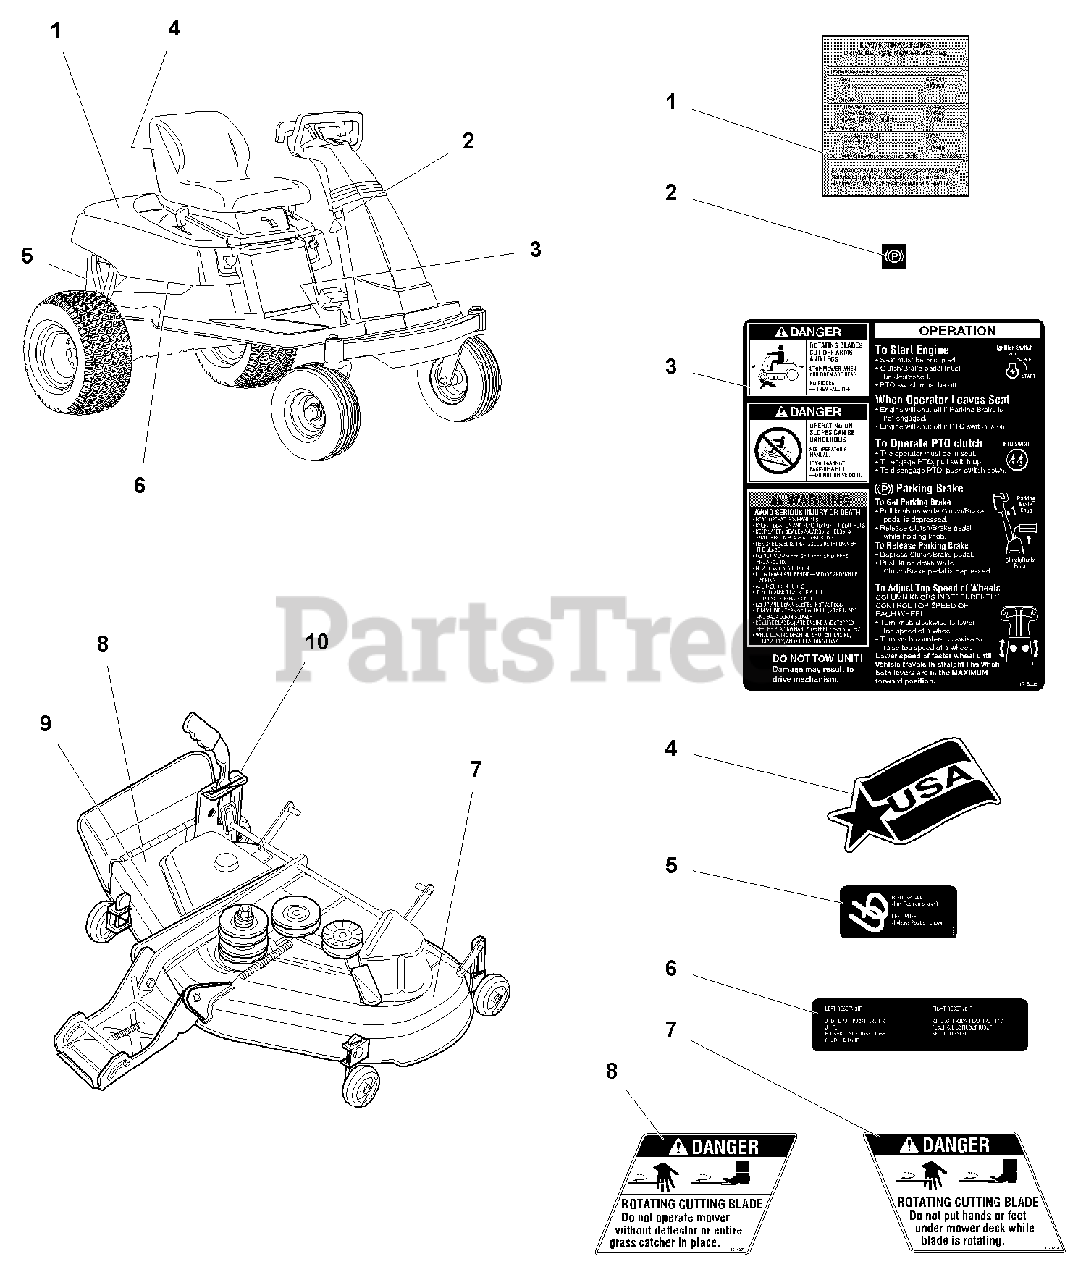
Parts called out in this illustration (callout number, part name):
1	DECAL, Belt/Blade (under Seat Deck)
2	DECAL, Parking Brake
3	DECAL, Operating Instructions
4	DECAL, Logo, USA
5	DECAL, Transmission Release
6	DECAL, Oil Reservoir
7	DECAL, Danger, Rotating Cutting Blade
8	DECAL, Danger, Chute in Place
9	DECAL, Cutting Width, 38"
9	DECAL, Cutting Width, 44"
9	DECAL, Cutting Width, 50"
10	DECAL, Height of Cut
